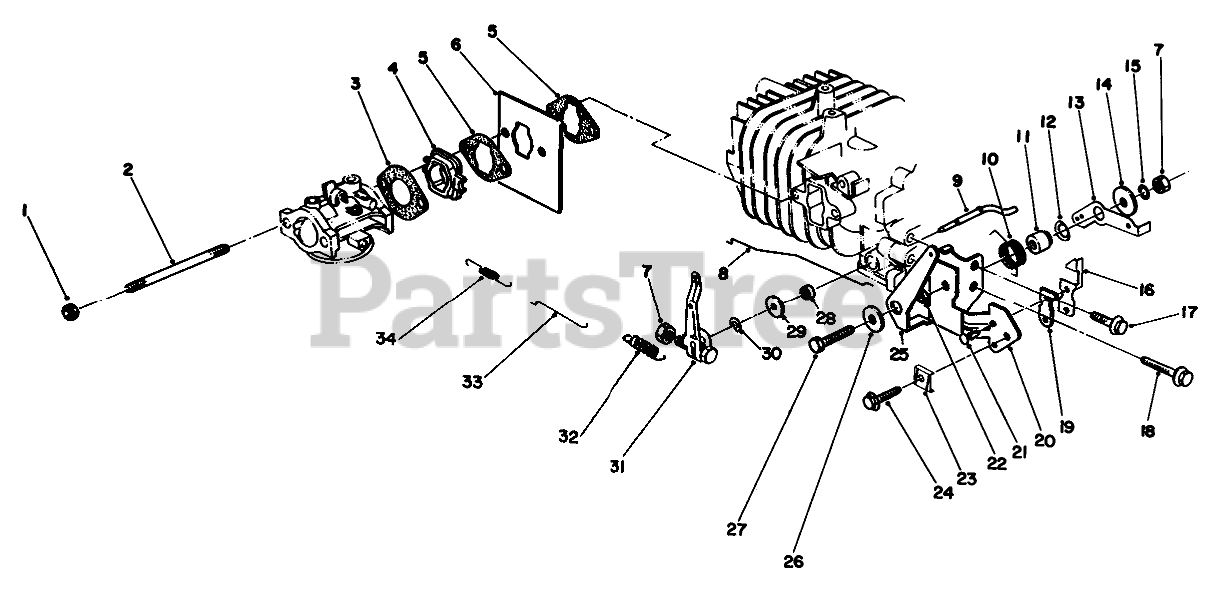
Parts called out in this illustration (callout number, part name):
1	NUT-LOCK
2	CARB STUD BOLT
3	GASKET-CARB
4	CUP - STARTER
5	GASKET
6	SHIELD
8	CHOKE ROD
9	Shaft-Govemor
10	SPRING-CHOKE LEVER
11	Gov Lever Spacer
12	Washer-Gov. Spring Lever
13	LEVER-SPRING, GOVERNOR
14	WASHER
15	LOCKWASHER
16	TERMINAL-KILL SWITCH
20	INSULATOR-KILL SWITCH
21	BRACKET-THROTTLE, CONTROL
22	KILL SWITCH RIVET
23	SPACER-CHOKE LEVER
24	CLAMP
26	LEVER-CONTROL, CHOKE
27	WASHER
29	SEAL-OIL
30	WASHER
31	E-RING
32	GOVERNOR ARM
33	SPRING-GOVERNOR
34	ROD-CARBURETOR
35	SPRING
